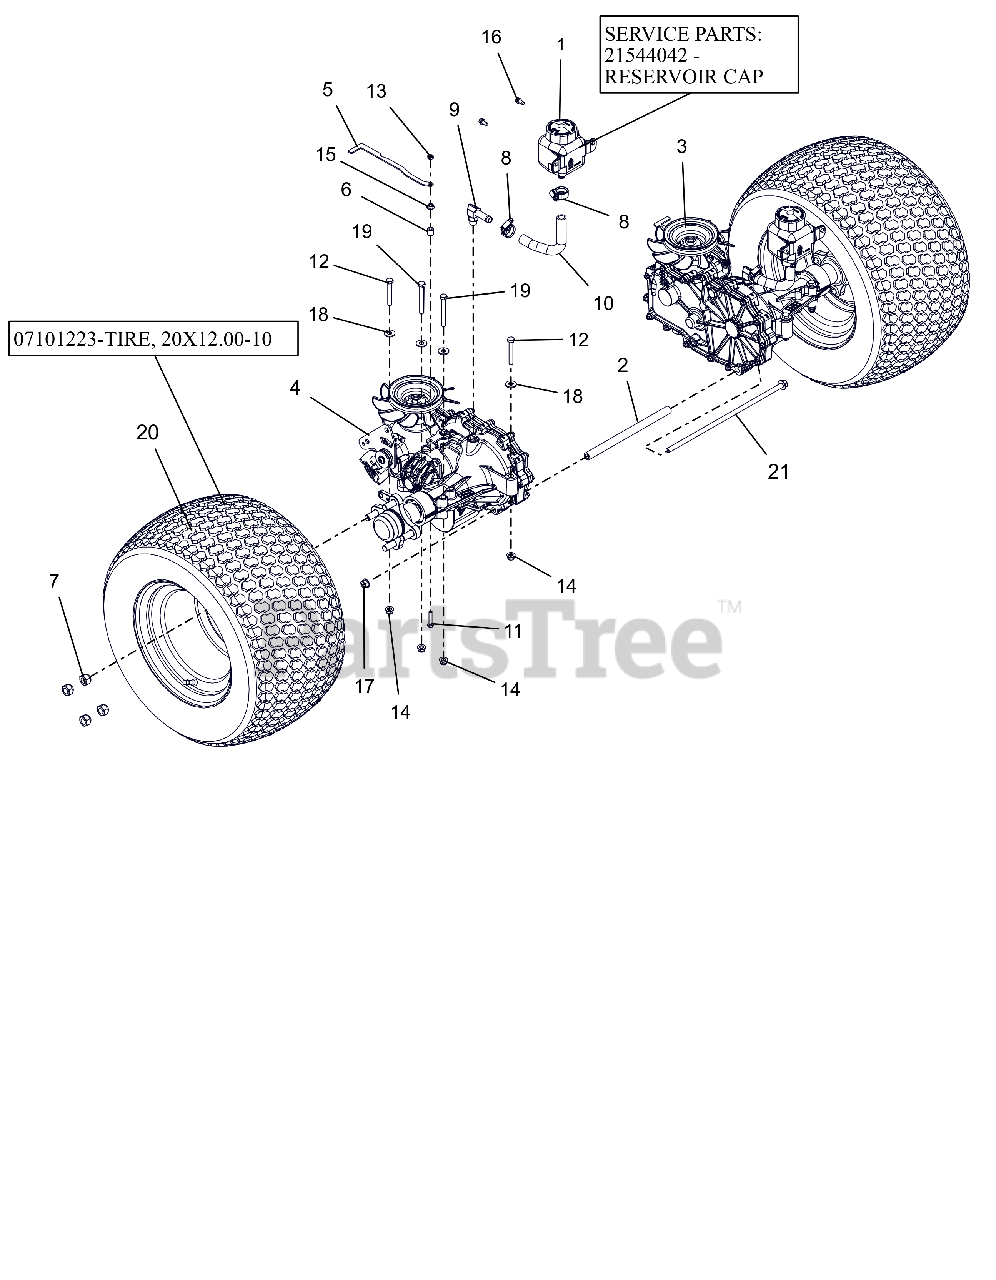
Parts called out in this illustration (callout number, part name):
1	TANK, EXPANSION
1	CAP, HYDRO RESERVOIR REPLAC.
2	SPCR, TRANSAXLE .406 ID X .630 OD X 9.27
3	TRANSAXLE,ZT2800 LH
4	TRANSAXLE,ZT2800 RH
5	BRKT, DUMP VALVE
6	BSHG-SLV .265X.500X.500
7	WHEEL NUT .500-20 YZ
8	CLAMP,.88 DIA. HOSE
9	FITTING, HYD (90 DEG)
10	HOSE, FORMED LH XL
11	@BLT-HEX .25-20X1.25 GR5 YWZC
12	@BLT-HEX .31-18X2.25 GR5 YWZC
13	NUT-LK-CTR JAM .25-20 YWZC
14	@NUT-LK-NYL-FLG .31-18 YWZC
15	@NUT-SPNLK-FLG .25-20 YWZC
16	SCR-TAP .25-20X.50 HWH TR YWZ
17	NUT-LK-CTR-FLG .375-16 GF ZCC
18	@WSHR-FL-STL.38X.875X.083 YWZC
19	@BLT-HEX .31-18X2.75 GR5 YWZC
20	ASM, WHL/TIRE 20X12.00-10
20	TIRE, 20X12.00-10 (OTR)
21	BLT,HEX-FLG .38-16X13 G5 ZCC
